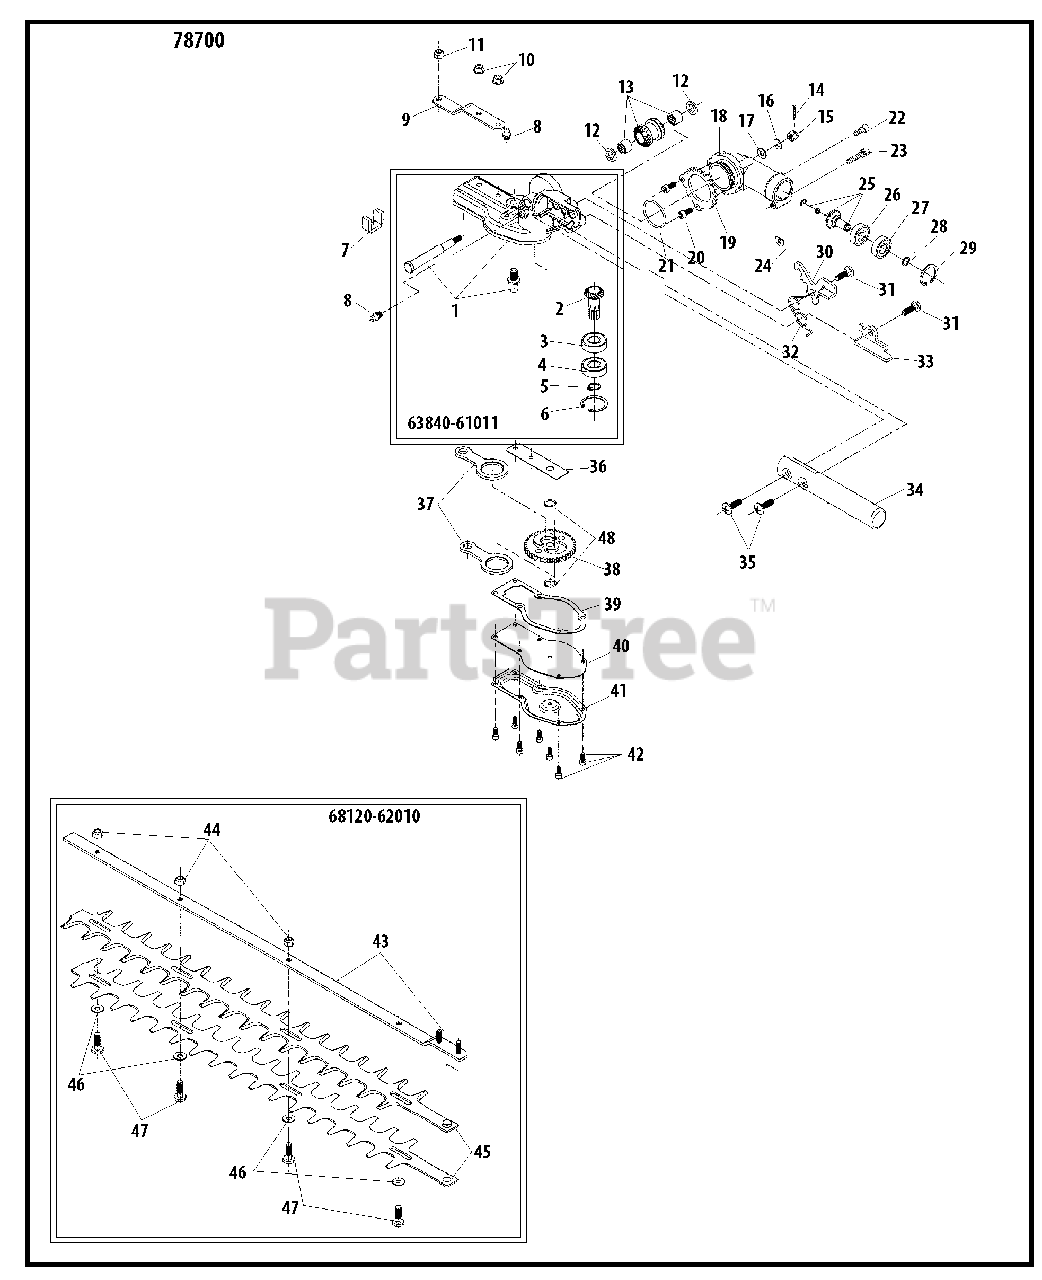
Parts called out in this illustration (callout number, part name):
1	CASE, GEAR - LOWER
2	GEAR - SHAFT
3	BEARING, BALL - 6001
4	BEARING, BALL - 6001ZZ
5	RING, RETAINING - 12
6	RING, RETAINING - 28
7	SEAL, FELT
8	FITTING, GREASE
9	BRACKET, CUTTER
10	NUT - 5 -- FLANGE
11	LOCKNUT - 6
12	COLLAR
13	GEAR SET - BEVEL
14	PIN, SPLIT
15	NUT - CASTLE
16	WASHER - CONICAL
17	WASHER - 6
18	CASE, GEAR - UPPER
19	PLATE, ADJUST
20	SCREW - 5X12
21	O-RING
22	SCREW - 5X12
23	SCREW - 5X25
24	SHIM
25	GEAR - BEVEL
26	BEARING, BALL - 609
27	BEARING, BALL - 609ZZ
28	RING, RETAINING
29	RING, RETAINING - 24
30	LEVER, LOCK
31	SCREW
32	SPRING
33	LEVER, LOCK
34	HANDLE
35	SCREW - 6X20
36	PLATE, GUIDE
37	ROD, CONNECTING
38	CAM GEAR
39	GASKET
40	PLATE, GEAR CASE
41	CASE, GEAR - LOWER
42	BLADE KIT - 22" (55cm)
43	GUIDE BAR - 22" (55cm)
44	LOCKNUT - 6
45	BLADE - 22" (55cm)
46	WASHER - 6
47	BOLT - 6X20
48	SPACER
